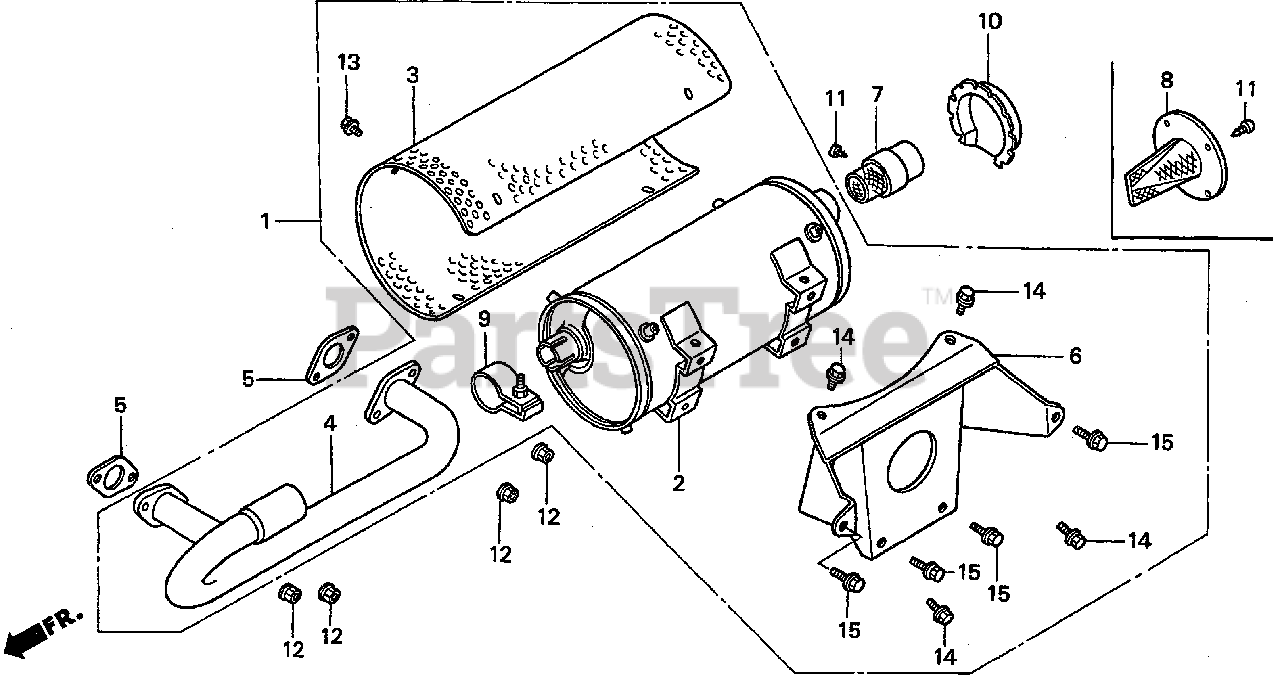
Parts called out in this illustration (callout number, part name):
1	MUFFLER KIT (HIGH-A) (N/A: SEE COMPONENTS)
2	MUFFLER (HIGH)
3	PROTECTOR, MUFFLER (HIGH)
4	PIPE, EX. (HIGH-R)
5	GASKET, EX. PIPE
6	STAY, MUFFLER (HIGH)
7	ARRESTER, SPARK
8	ARRESTER, SPARK (SIDE)
9	BAND ASSY.
10	DEFLECTOR KIT, EX.
11	SCREW (NELSON)
12	NUT, FLANGE (8MM)
13	BOLT, FLANGE (6X8)
14	BOLT, FLANGE (8X14)
15	BOLT, FLANGE (8X20)
